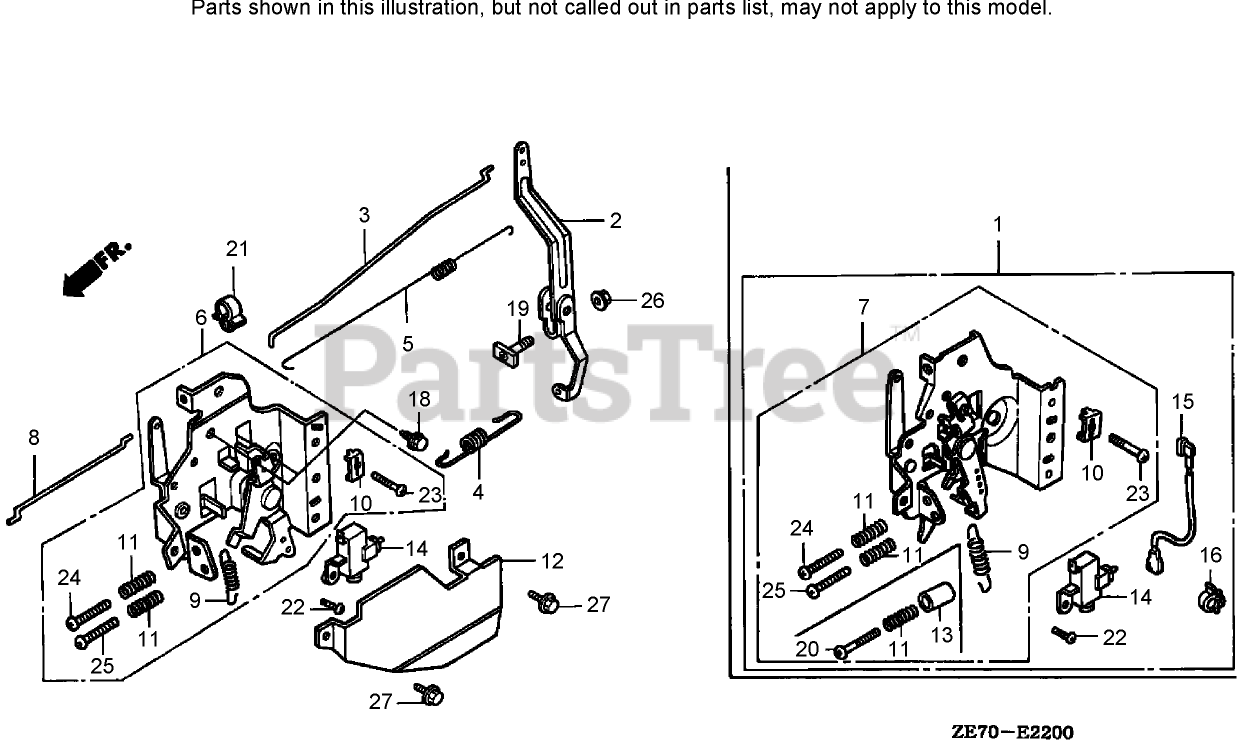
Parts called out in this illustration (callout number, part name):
2	Arm-Governor
3	Rod-Governor
4	Spring-Governor (STD)
5	SPRING-RETURN, THROTTLE
6	CONTROL ASM
8	Rod-Choke
9	Spring-Lever
10	Holder-Cable
11	SPRING-ADJUSTING, CONTROL
12	Protector-Control
14	ENGINE STOP SWITCH ASM
18	BOLT-FLANGE (6X12) (C T200)
19	BOLT-ARM, GOVERNOR
21	CLIP-HARNESS, WIRE
22	Screw-Pan (4X8)
23	Screw-Pan (5X16)
24	Screw-Pan (5X20)
25	Screw-Pan (5X28)
26	NUT-FLANGE (6 mm)
27	Bolt-Flange (6X10)
